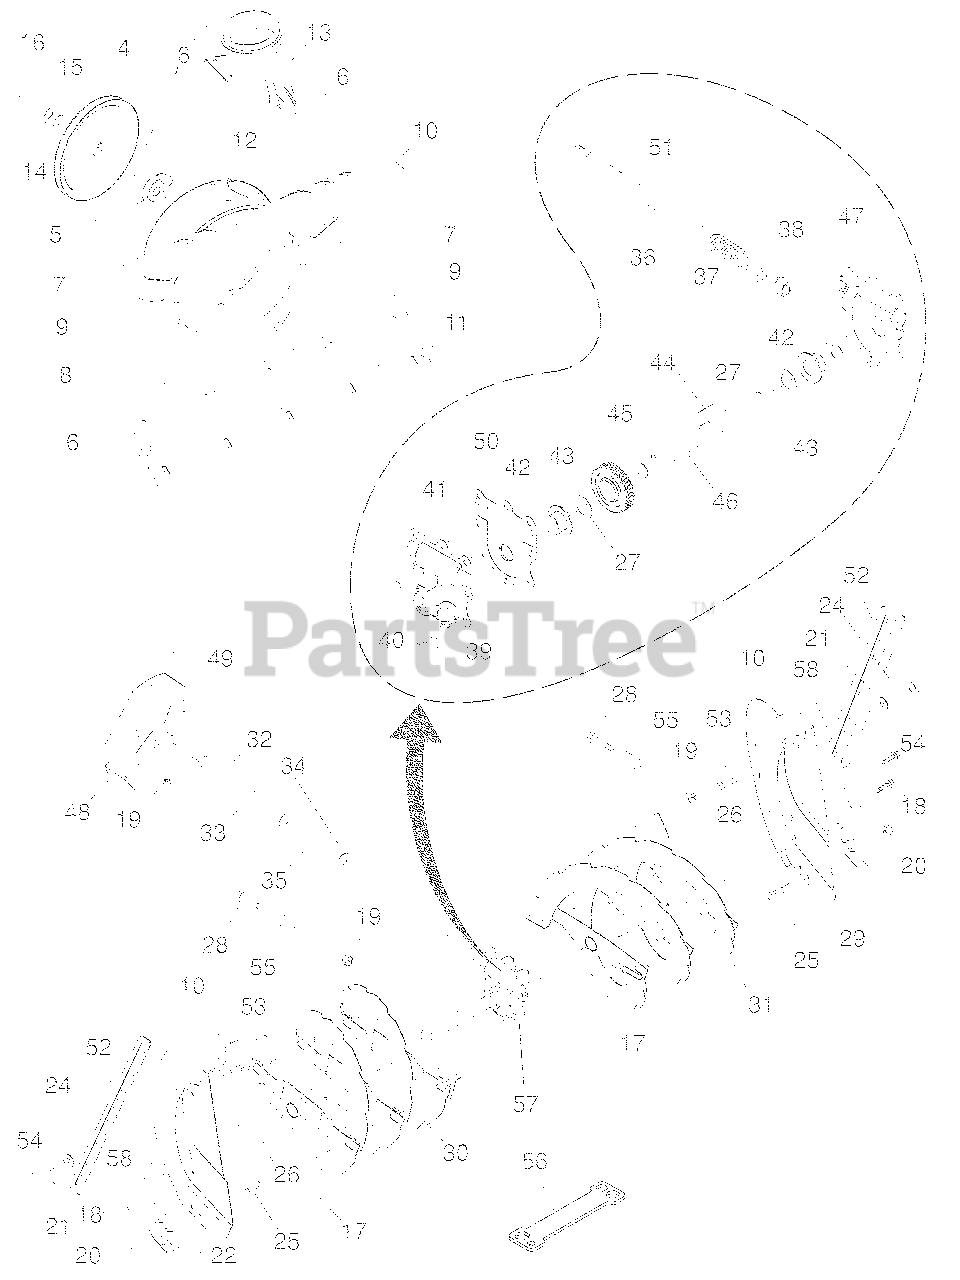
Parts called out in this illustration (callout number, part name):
4	Pulley, Impeller
5	Bearing Assembly, Flange
6	Nut, Hex Flange 5/16-18
7	Bolt, Flat Head, Carriage 5/16-18 x 5/8
8	Bolt, Carriage 5/16-1 8 x 5/8
10	Housing, Auger
11	Bar, Scraper
12	Bracket, Corner Discharge
13	Base, Discharge Chute
14	Washer, Lock 5/16
15	Washer, Flat
16	Screw, Hex Head 5/16-18 x 3/4
17	Grease Fitting
18	Screw, Hex Head 5/16 x 1
19	Nut, Hex Lock 1/4-20
20	Nut, Hex Lock 5/16-18
21	Washer, Flat 5/16
22	Skid Plate, Heavy Duty
25	Bolt, Shoulder 1/4-20
26	Retainer, Plastic
27	Washer, Thrust, 1"
28	Bolt, Shear
29	Skid Plate, Heavy Duty
30	Auger Assembly, RH
31	Auger Assembly, LH
33	Bushing, Flange 3/4
34	Washer, Thrust 3/4
35	Bearing, Thrust 3/4
36	Shaft, Impeller
37	Washer, Thrust 5/8
38	Bushing, Flange 5/8
39	Screw, Hex Head 5/16-18 x 3/4
40	Plug, Case
41	Housing, Gearbox, RH
42	Seal, Oil
43	Bushing, Flange, 1"
44	Key, Square 1/4 x 1/4 x 7/8
45	Gear, Worm
46	Shaft, Auger
47	Housing, Gearbox, LH
48	Impeller Assembly
49	Screw, Hex Head 1/4-20 x 1-5/8
50	Gasket, Gearbox
51	Pin, Roll 3/16 x 1-1/8
52	Bar, Drift Cutter
53	Bolt
56	Multi-Wrench
57	Gearbox Assembly
